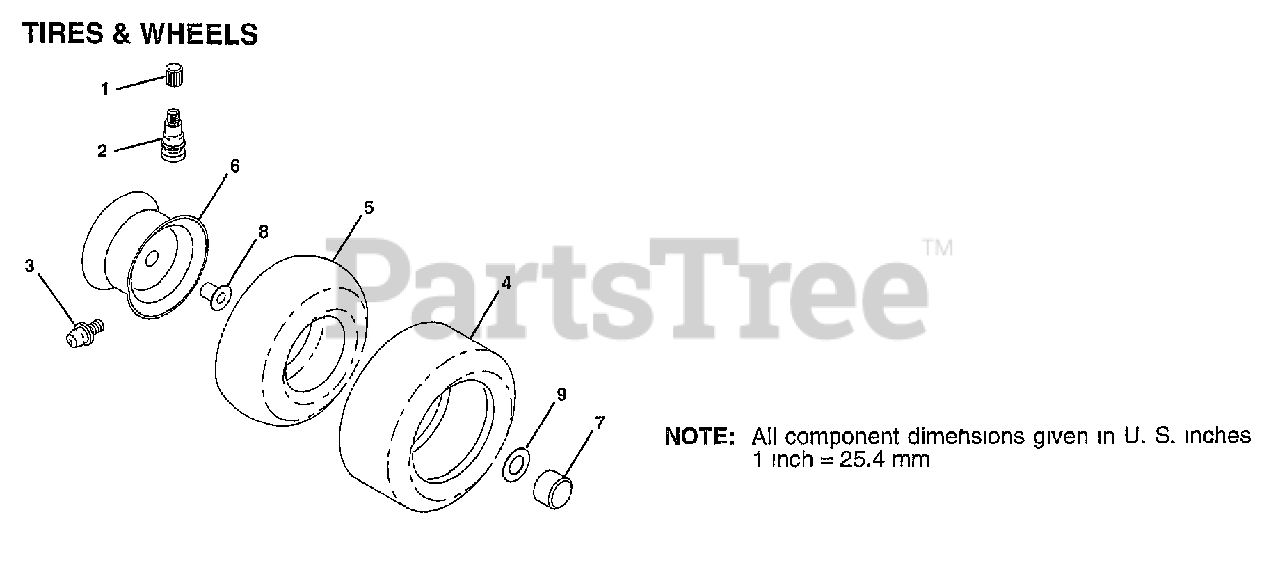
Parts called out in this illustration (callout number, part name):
2	VALVE STEM LT
3	FITTING LT
5	TUBE.5.3/4.5/6
5	TUBE.16X6.5/7.5-8
6	"RIM FRONT 6"""
6	"RIM ASM REAR 8"""
7	HUB CAP
8	"FLANGE, BEARING"
9	WASHER
